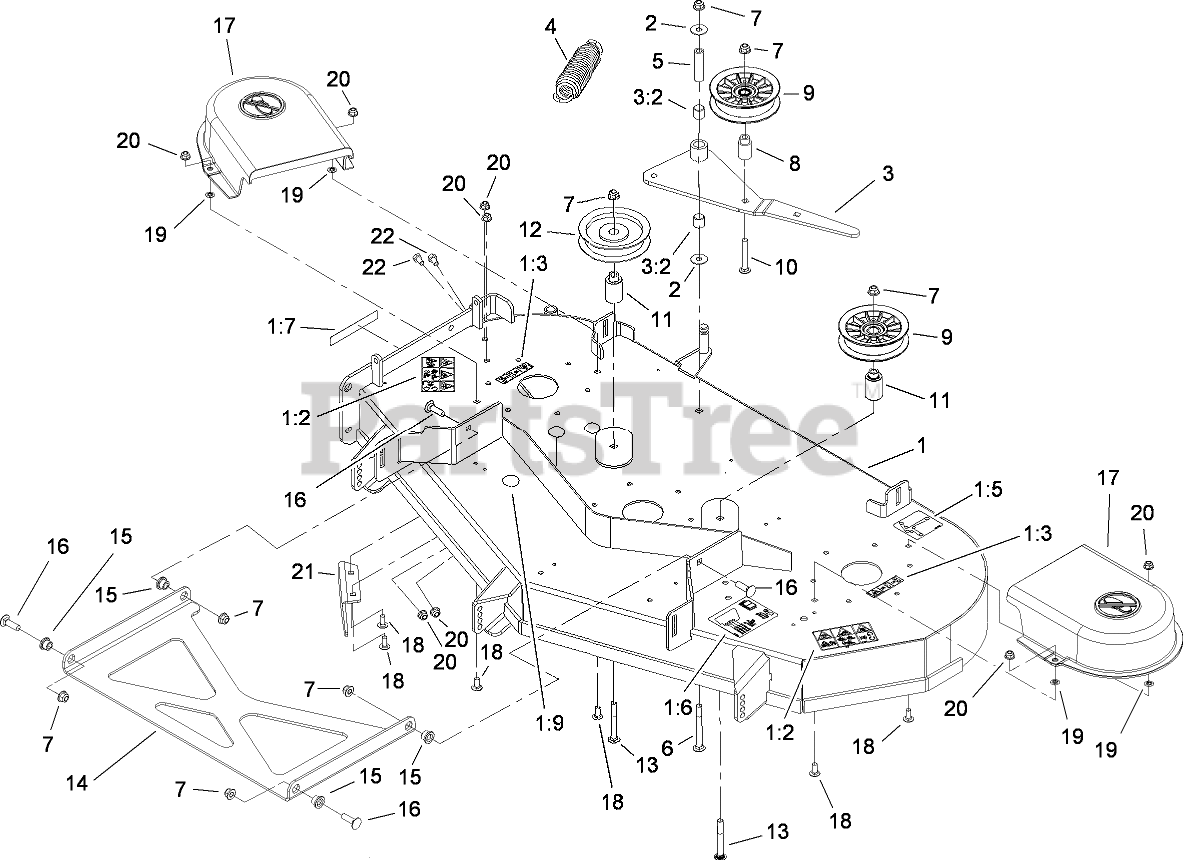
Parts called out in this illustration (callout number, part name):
1	48 INCH DECK ASM
1:2	DECAL-DANGER
1:3	DECAL-WARNING, BELT SHIELD
1:5	DECAL-BELT ROUTING
1:6	DECAL-ROLLER, ANTI-SCALP
1:7	DECAL-DANGER
1:9	DECAL-COVER, HOLE
2	WASHER
3	IDLER ARM ASM
3:2	SLEEVE-BEARING
4	Spring-Extension
5	BUSHING-PIVOT, IDLER
6	SCREW-CARR
7	NUT-HF, NI
8	BUSHING-IDLER
9	SHEAVE AND BEARING ASM
10	SCREW-CARR
11	BUSHING-IDLER
12	PULLEY-IDLER
13	BOLT-CARRIAGE
14	STRUT-DECK
15	BUSHING-FLANGED
16	BOLT-CARR
17	SHIELD-BELT
18	SCREW-CARR
19	RING-RETAINING, BOLT
20	NUT-HF, NI
21	BAFFLE-DISCHARGE
22	SCREW-HH
